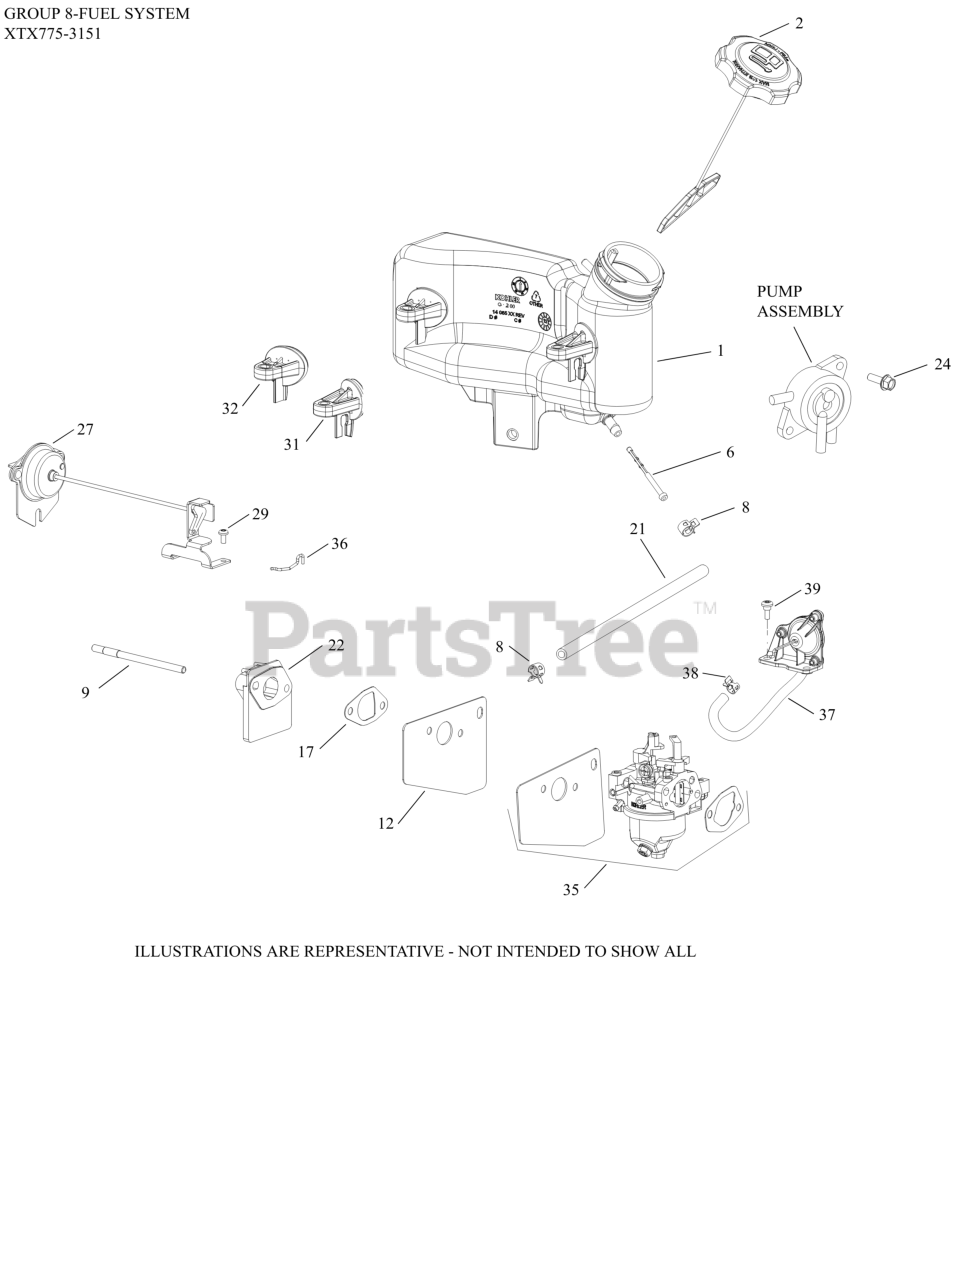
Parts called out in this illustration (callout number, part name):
1	TANK, FUEL
2	FUEL CAP ASSEMBLY
6	FILTER, FUEL IN-NIPPLE
8	CLAMP, HOSE (NON-CALIF)(#1423710S)
9	STUD,M6X1.0X100.2MM
12	KIT, CARBURETOR HEAT SHIELD GASKET
17	KIT, INTAKE GASKET
21	HOSE, FUEL LOW-PERMEATION
22	KIT, SPACER
24	SCREW, HEX FLANGE (M6)
27	ARM ASSY,AUTO CHOKE-USE 14 187 18-S
29	SCREW, M4 THRD FRMNG-(#25086439S)
31	BRACKET, FUEL TANK
32	BRACKET, FUEL TANK
35	KIT, CARBURETOR 13 MM AUTO CHOKE
36	LINKAGE, AUTO CHOKE
37	DIAPHRAGM, ASSEMBLY
38	CLAMP, HOSE
39	SCREW, SHOULDER-(#25086440S)
NI	KIT, HIGH ALTITUDE - USE 14 755 04-S
NI	KIT, HIGH ALTITUDE (ABOVE 8,000 FT.)
NI	KIT, CARBURETOR REPAIR (RUIXING)
